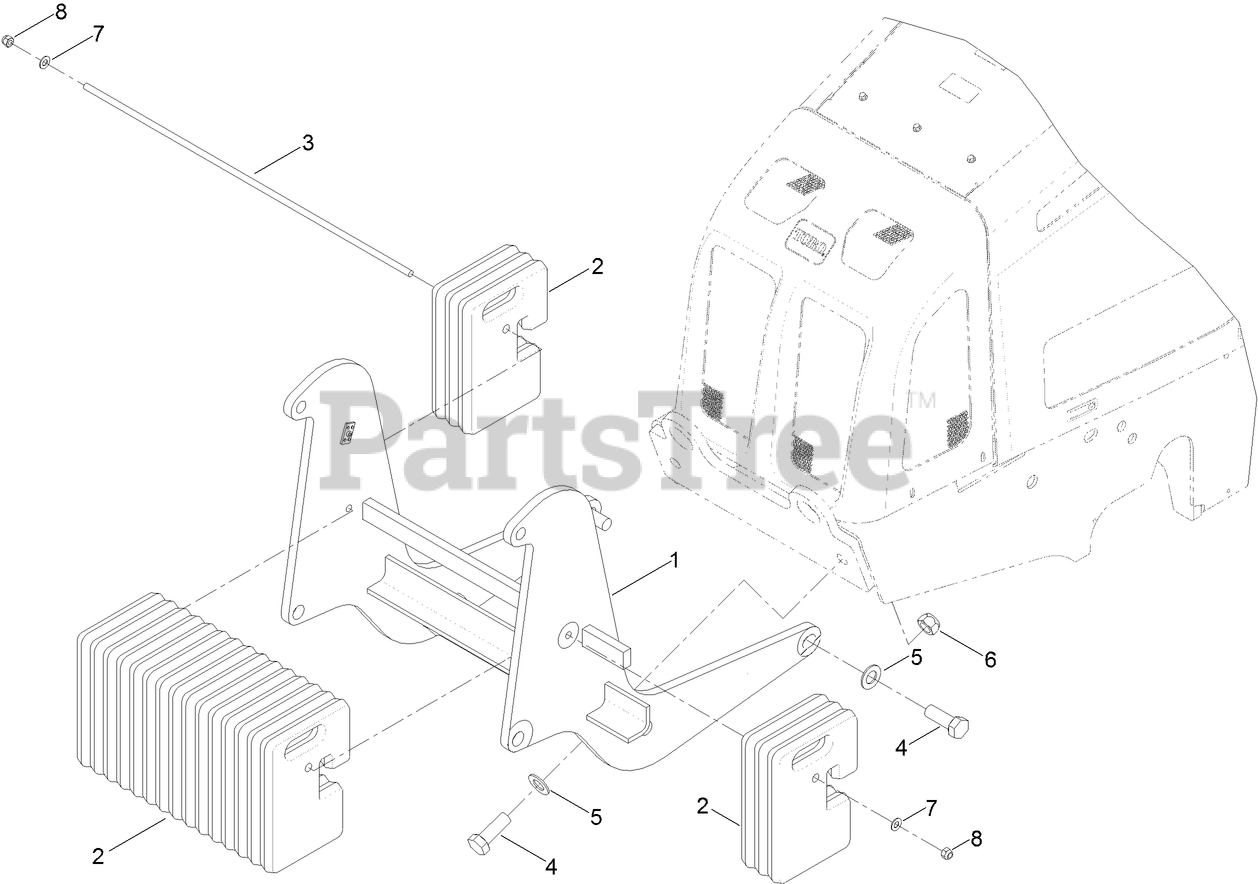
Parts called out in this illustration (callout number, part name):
1	FRAME-COUNTERWEIGHT
2	COUNTERWEIGHT-60lb
3	ROD-WEIGHT
7	WASHER-FLAT
8	NUT-LOCK, HEX
